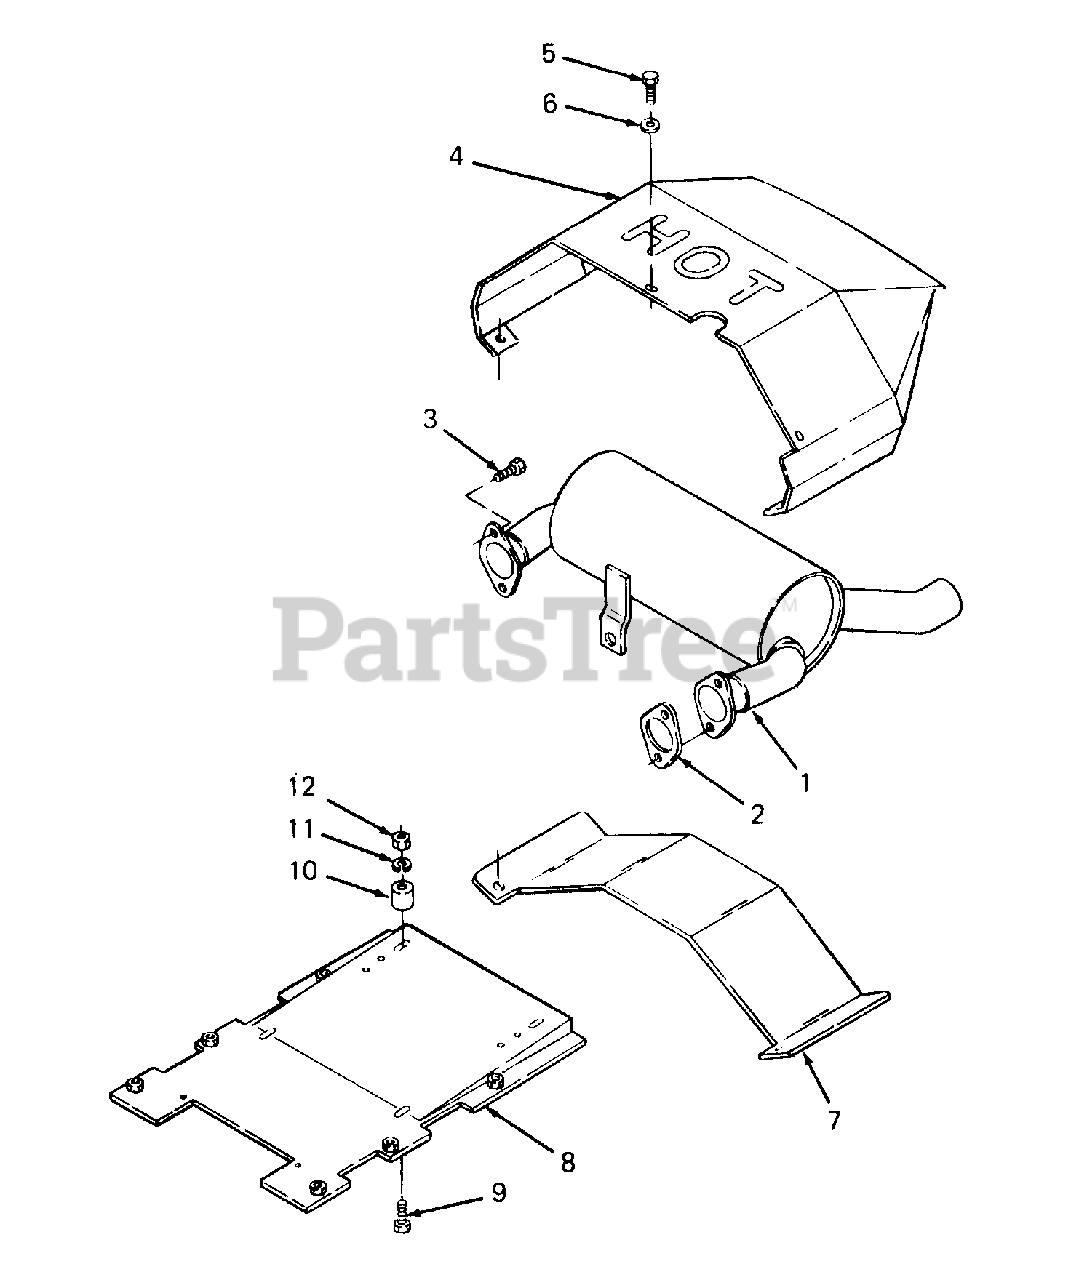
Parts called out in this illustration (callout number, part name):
2	Gasket, Exhaust
3	Screw, Sems
4	Ducting, Muffler
5	Bolt, Hex, M6-1.0 X 10 mm Lg GR5
6	Washer, Flat, .281 X .50 X .063 Thk
7	Shield, Muffler Heat
9	Screw, Hex Cap, 5/16-18 X 3.25 Lg GR5
11	Washer, Lock, 5/16
12	Nut, Hex, 5/16-18
